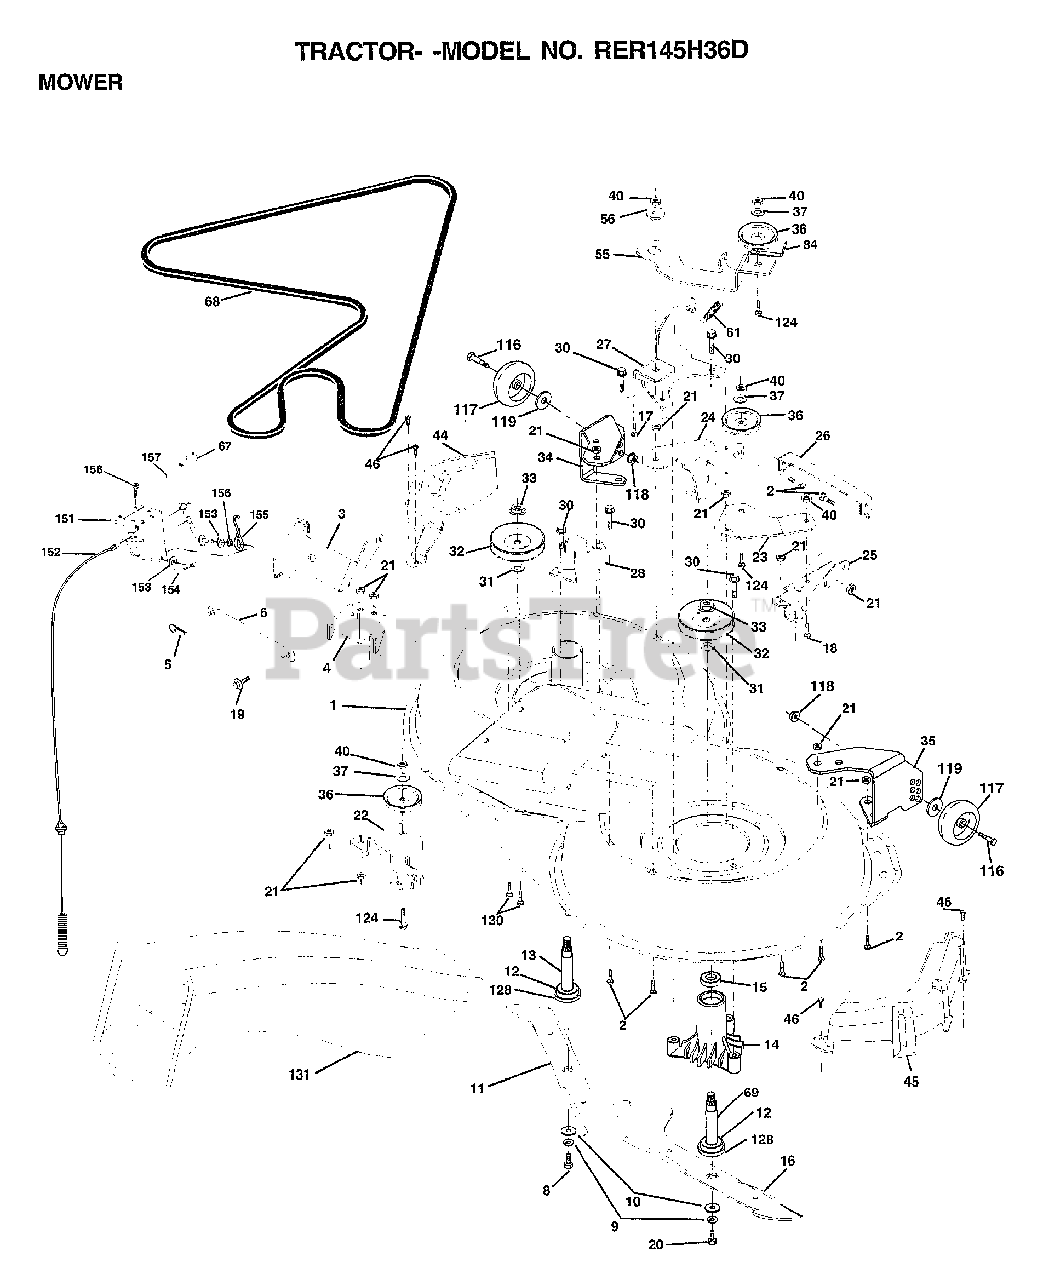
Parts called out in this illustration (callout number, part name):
1	HOUSING.ASM.MOWER
2	BOLT
3	BRKT.ASM.S-BAR.CHASSIS
4	BRKT.BAR.SWAY.DECK
6	BAR.SWAY.92.CRD
8	BLADE BOLT
10	WASHER.HARD.BLADE
11	BLADE
12	BEARING.BALL
14	HSG ASM MANDREL
15	BEARING
16	BLADE
17	BOLT.3/8-14X1.25
18	BOLT D
19	BOLT SHD 5/16-18
20	BOLT.3/8-24X1.25
22	BRKT.IDLER.SPRT.CRD
23	"BRKT.IDLER.SPRT.RF.92,CRD"
24	BRKT.SUSP.LF.92.CRD
25	BRKT.SUSP.RF.92.CRD
26	BRACE.SUPT.SUSP.FRT.CRD
27	BRKT.ASM.SUSP.RR.92.CRD
28	BRKT.ASM.SUSP.LR.92.CRD
30	"SCREW-THD ROLL,WA"
31	WASHER
32	PULLEY.MAND.36/46
34	BRKT.GUAGE.WHL.LF.92.CRD
35	BRKT.GUAGE.WHL.RF.92.CRD
36	PULLEY.IDLER.4.25
37	WASHER
44	COVER.MANDREL.LH.92.CRD
45	COVER.MANDREL.RH.92.CRD
46	SCREW.1/4-20X5/8
55	ARM.IDLER.92.CRD
56	SPACER.RETAINER.MOWER
61	SPRING.TENSION.BELT
67	KNOB T(3/8 HOLE)
68	HEX-BELT.92.MWR.105AA
69	SHAFT.ASM.W/LWR.BRG.RH.THD
84	"KEEPER-BELT,IDLER"
116	BOLT.SHOULDER
117	WHEEL GAGE DONUT
118	LOCKNUT
119	WASHER
124	BOLT.3/8-16X1.50
128	WASHER.FELT.
131	CHUTE.BAGGER.CRD
151	BRKT CLUTCH CABLE
152	CABLE CLUTCH CRD SERVICE
153	WASHER FLAT
154	SPRING RETAINER
155	SPRING RETENTION LVR CLUTCH CAB
156	SPACER
157	ROD.CLUTCH.CABLE.3/8
158	SCREW LT
